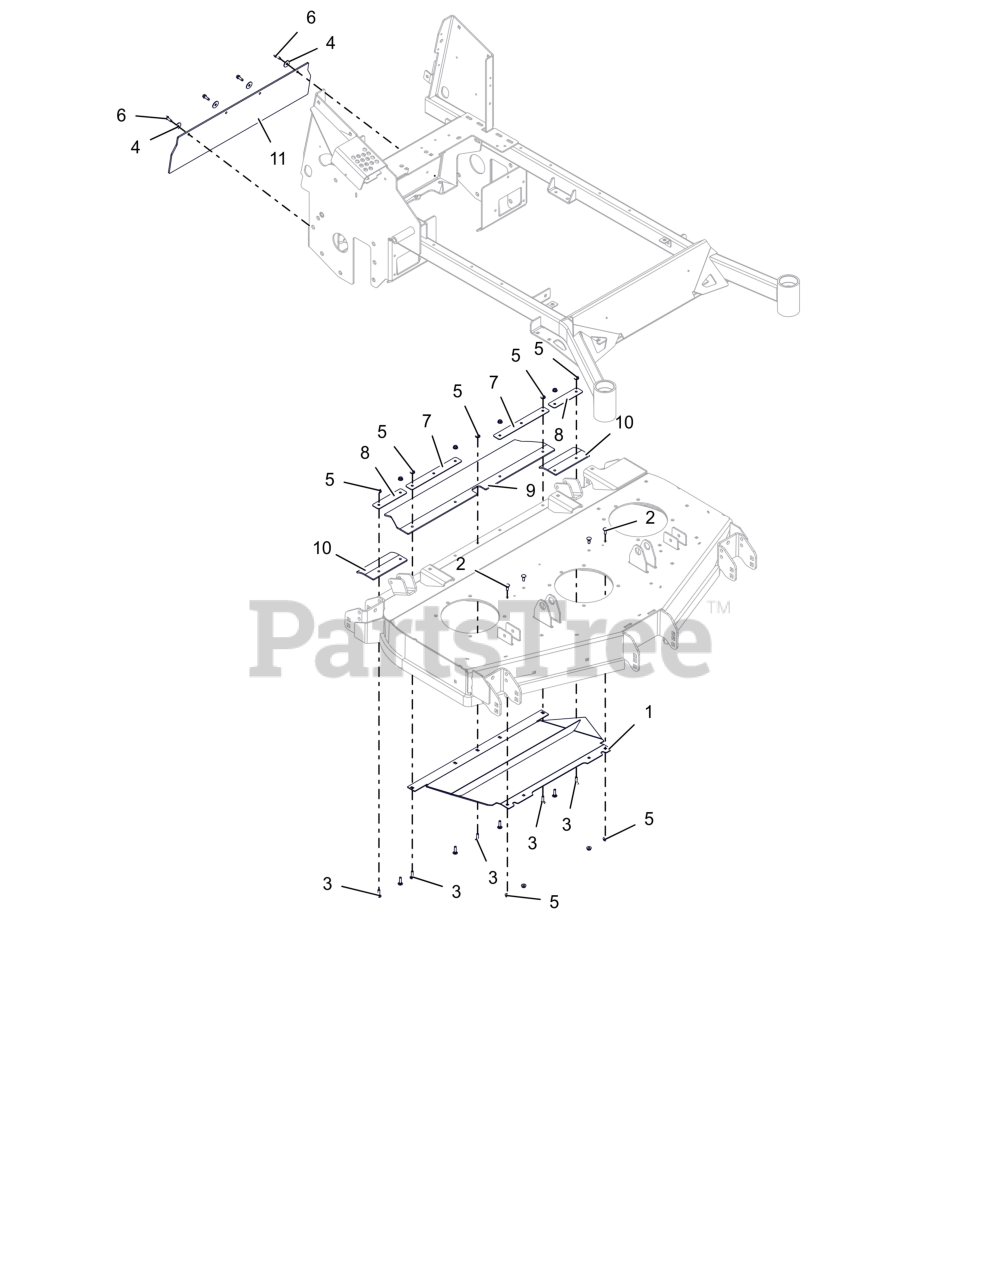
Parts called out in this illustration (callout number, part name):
1	WLDMT, DEFLECTOR BAFFLE (RED)
2	BLT, RHSN .25-20X.750 G5 ZCC
3	BLT, RHSN .25-20X1.00 G5 ZCC
4	WSHR,FLT .281X1.000X.063 ZCC
5	NUT-LK-CTR-FLG .25-20 ZC120
6	SCR,TAP .25-20X.75 HWH TR ZCC
7	PLATE, CHUTE MTG (BLACK)
8	PLATE- 52" TIRE CHUTE MTG
9	CHUTE- REAR DISCHARGE 6.5 IN
10	FLAP- REAR DISCHARGE 48" TIRE
11	CHUTE, REAR DISCHARGE
